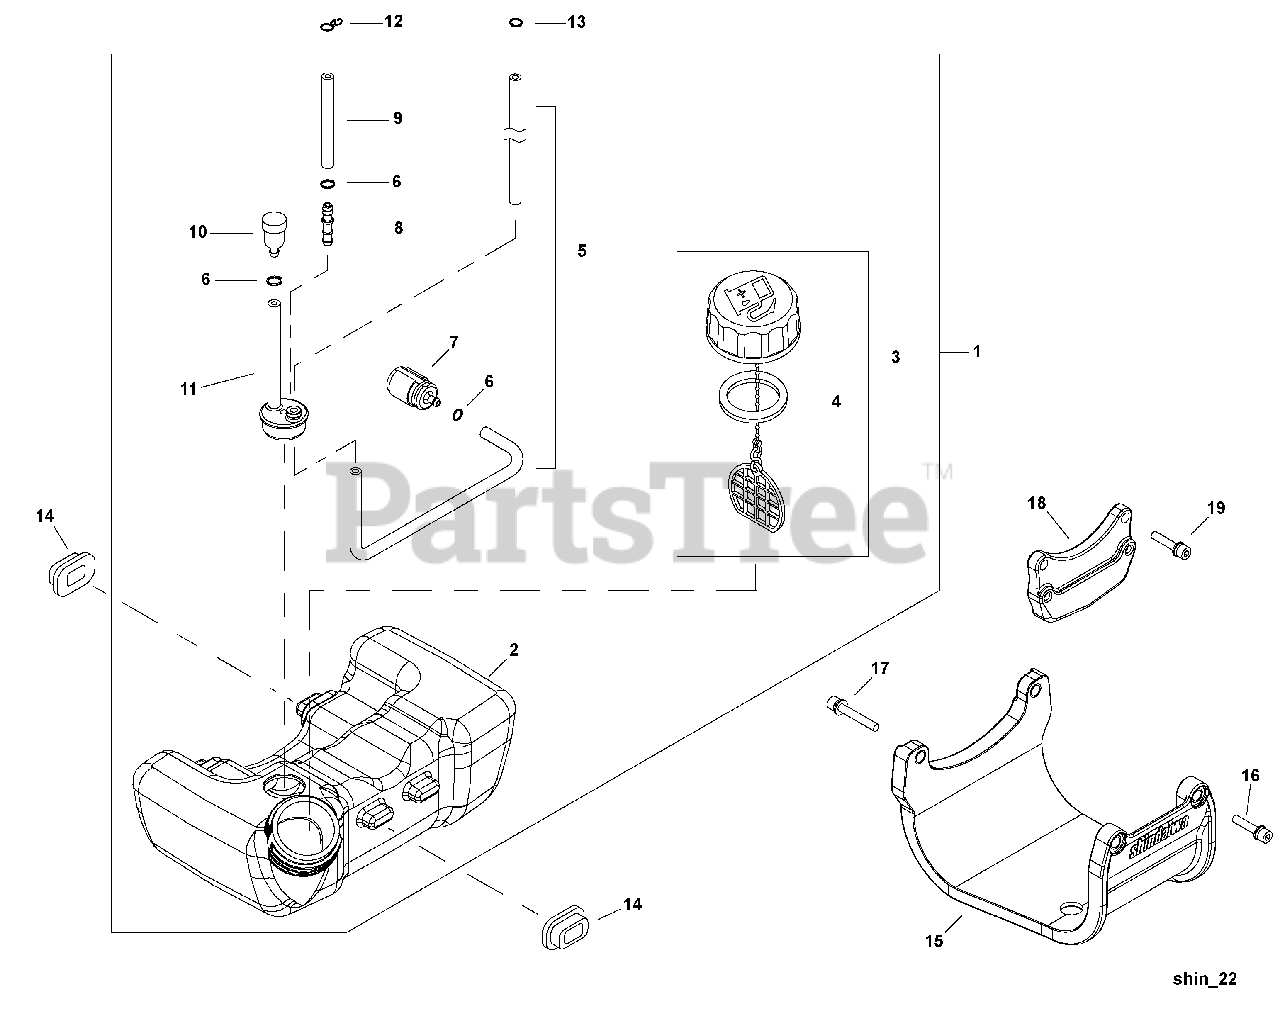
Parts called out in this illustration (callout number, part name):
1	FUEL TANK ASSY
2	TANK, FUEL
3	CAP ASSY
4	GASKET, CAP
5	PIPE - FUEL
6	RING, RETAINING - 6
7	FILTER, FUEL
8	CONNECTOR, PIPE
9	PIPE - RETURN
10	VENT, FUEL TANK
11	PIPE ASSY
12	CLIP - SPRING
13	RING, RETAINING - 6
14	CUSHION, FUEL TANK
15	GUARD, FUEL TANK
16	SCREW - 5X20
17	SCREW - 5X40
18	METAL FUEL TANK BRACKET
19	SCREW - 5X20
